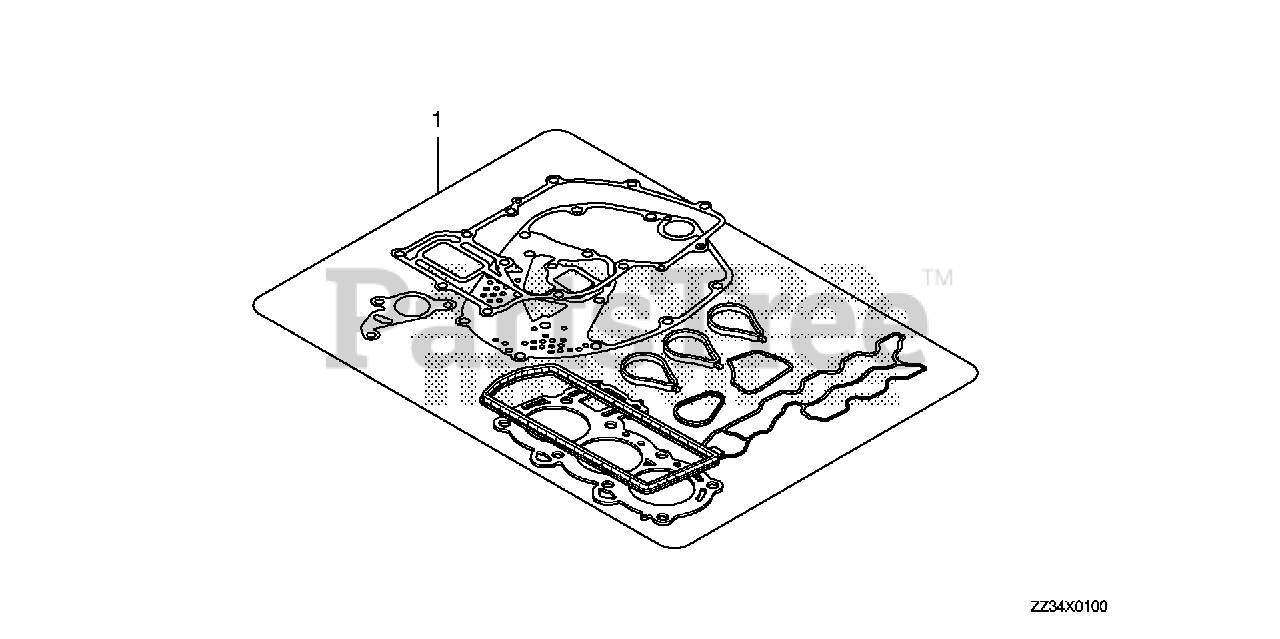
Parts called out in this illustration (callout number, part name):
1	GASKET KIT (BF60) (COMPONENT PARTS)
1	GASKET, OIL PAN
1	GASKET, CYLINDER HEAD
1	GASKET, HEAD COVER
1	GASKET, IN. MANIFOLD
1	GASKET, EX. PIPE
1	O-RING, THERMOSTAT COVER
1	GASKET, EX. WATER JACKET COVER
1	GASKET, MOUNT CASE
1	GASKET, REGULATOR
